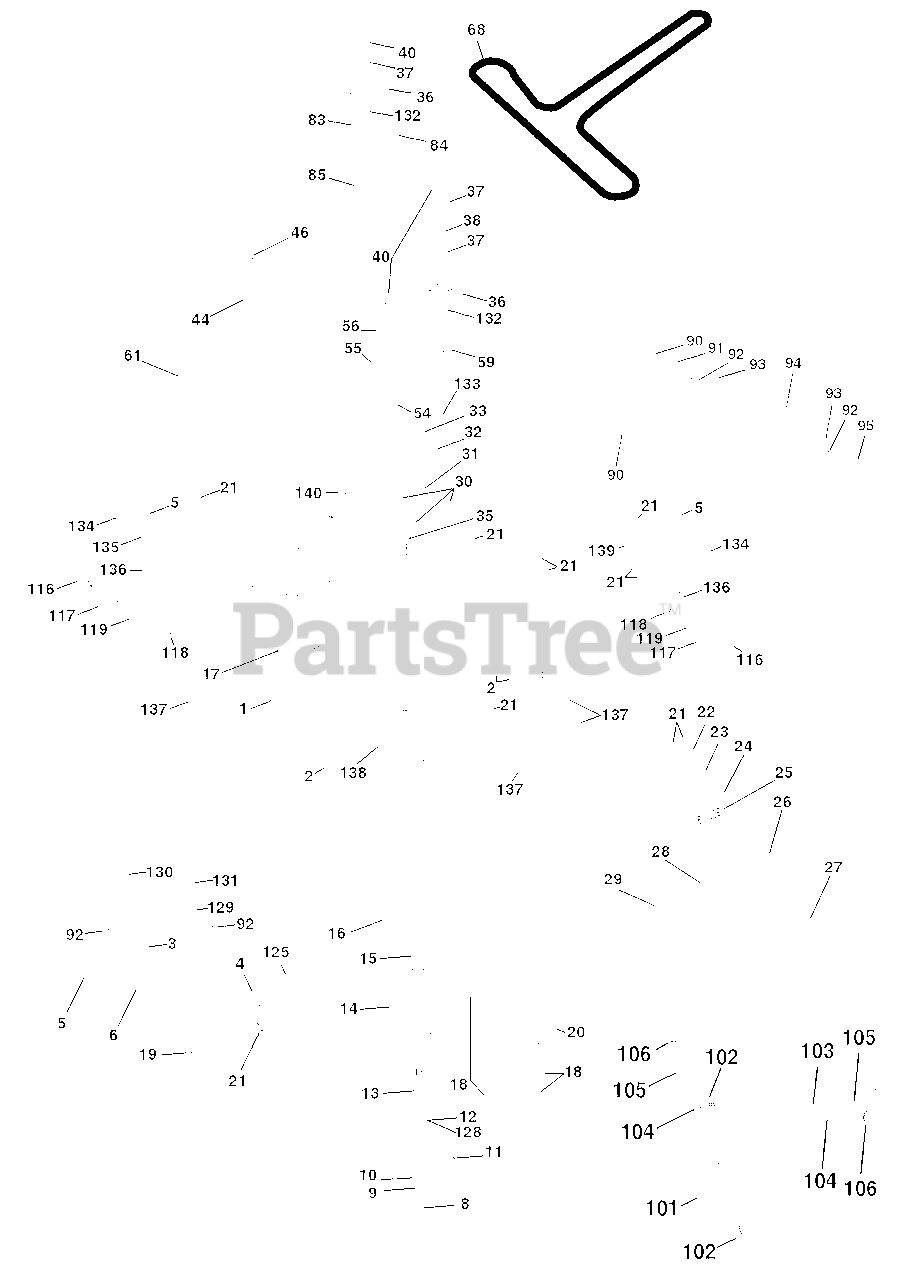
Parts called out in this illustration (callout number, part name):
1	Deck Weldment MWR HD 42" Adj.
2	Bolt Rdhd Sqnk 5/16-18unc X3/4
3	Bracket Asm Fr Sway Bar 38/42
4	Bracket Asm Deck 42"sway Bar
5	Retainer Spring
6	Arm Suspension Rear
8	Bolt 3/8-24x1 25 Gr8 Patched
9	Washer Lock Hvy 3/8 Unplated
10	Washer Hard Blade Mower Vented
11	Blade Mower Mulching 42"
12	Bearing Ball #6204 (Mandrel)
13	Shaft Asm W/lower Bearing
14	Housing Mandrel Vented(machd)
15	Bearing Ball Mandrel
16	Stripper Round Mower
17	Bolt Rdhd Sqnk 3/8-16 X 2-1/4
18	Bolt Carr 5/16-18 X 5/8
19	Bolt Shoulder
20	Baffle Vortex 42
21	Nut Crown Lock 5/16-18
22	Stiffener Bracket 42"deck
23	Bracket Deflector Mower 42"
24	Cap Sleeve 80x 112 Blk Mower
25	Spring Torsion Deflector 2 52
26	Nut Push Phos & Oil
27	Shield Deflector Mower 42" Blk
28	Washer 11/32 X 5/8 X 16 Ga
29	Rod Hinge 42"6 75 Wlg
30	Screw Thdrol Wsh Hd
31	Washer Spacer Mower Vented
32	Pulley Mandrel 42"
33	Nut 9/16top Lock Flng Cntr
35	Fastner Christmas Tree
36	Pulley Idler Flat 3 060
37	Washer 13/32 X 13/16 X 16 Ga
38	Spacer Spring Stop Idler
40	Nut Lock 3/8-16 Unc
44	Guard Mandrel LH Black
46	Screw Thdrol 1/4-20x5/8
54	Washer Hardened
55	Arm Idler 42"mower LT/YT
56	Spacer Retainer Pm Mower
59	Guard, Belt
61	Spring Ext. Elect
68	V-Belt Mower
83	Washer Sintered
84	Keeper 'Belt Idler
85	Bolt Carriage 3/8-16 x 2-1/4 Gr.5
90	Bolt Fin Hex 3/8-16unc X 1
91	Bracket Asm Noseroller LH
92	Nut Lock Hex w/ins. 3/8-16 UNC
93	Washer 17/32 X 7/8 X 16 Ga
94	Roller Nose 38 & 42
95	Bracket Asm Noseroller RH
101	Cover Mulching 42" Blk
102	Screw
103	Washer #10
104	Washer Lock #10
105	Latch Asm Bagger
106	Nut Weld .327/.304 #10-24
116	Bolt Shld
117	Wheel Gauge Donut
118	Nut Centerlock 3/8 - 16 UNC
119	Washer 3/8 x 7/8 x 14 Ga.
125	Cotter Pin
128	Washer Felt
129	Washer 13/32 x 13/16 x 12 Ga.
130	Bolt Fin Hex 3/8-16unc x 1 Gr. 5
131	Bolt Rdhd Sqnk 3/8-16 UNC x 1
132	Washer 13/32 x 1-3/8 x 3 Ga.
133	Bolt RDHD 3/8-16 UNC x 2-3/4 Gr.5
134	Pin Head Rivet
135	Bracket Asm Whl Ga Rear Lh 42"
136	Bar Ajusting Gauge Wheel
137	Bolt Carr 5/16-18 x 5/8 Short
138	Bracket Asm Whl Ga Rear Rh 42"
139	Bracket Asm Whl Ga Front Rh 42"
140	Bracket Asm Whl Ga Front Lh 42"
